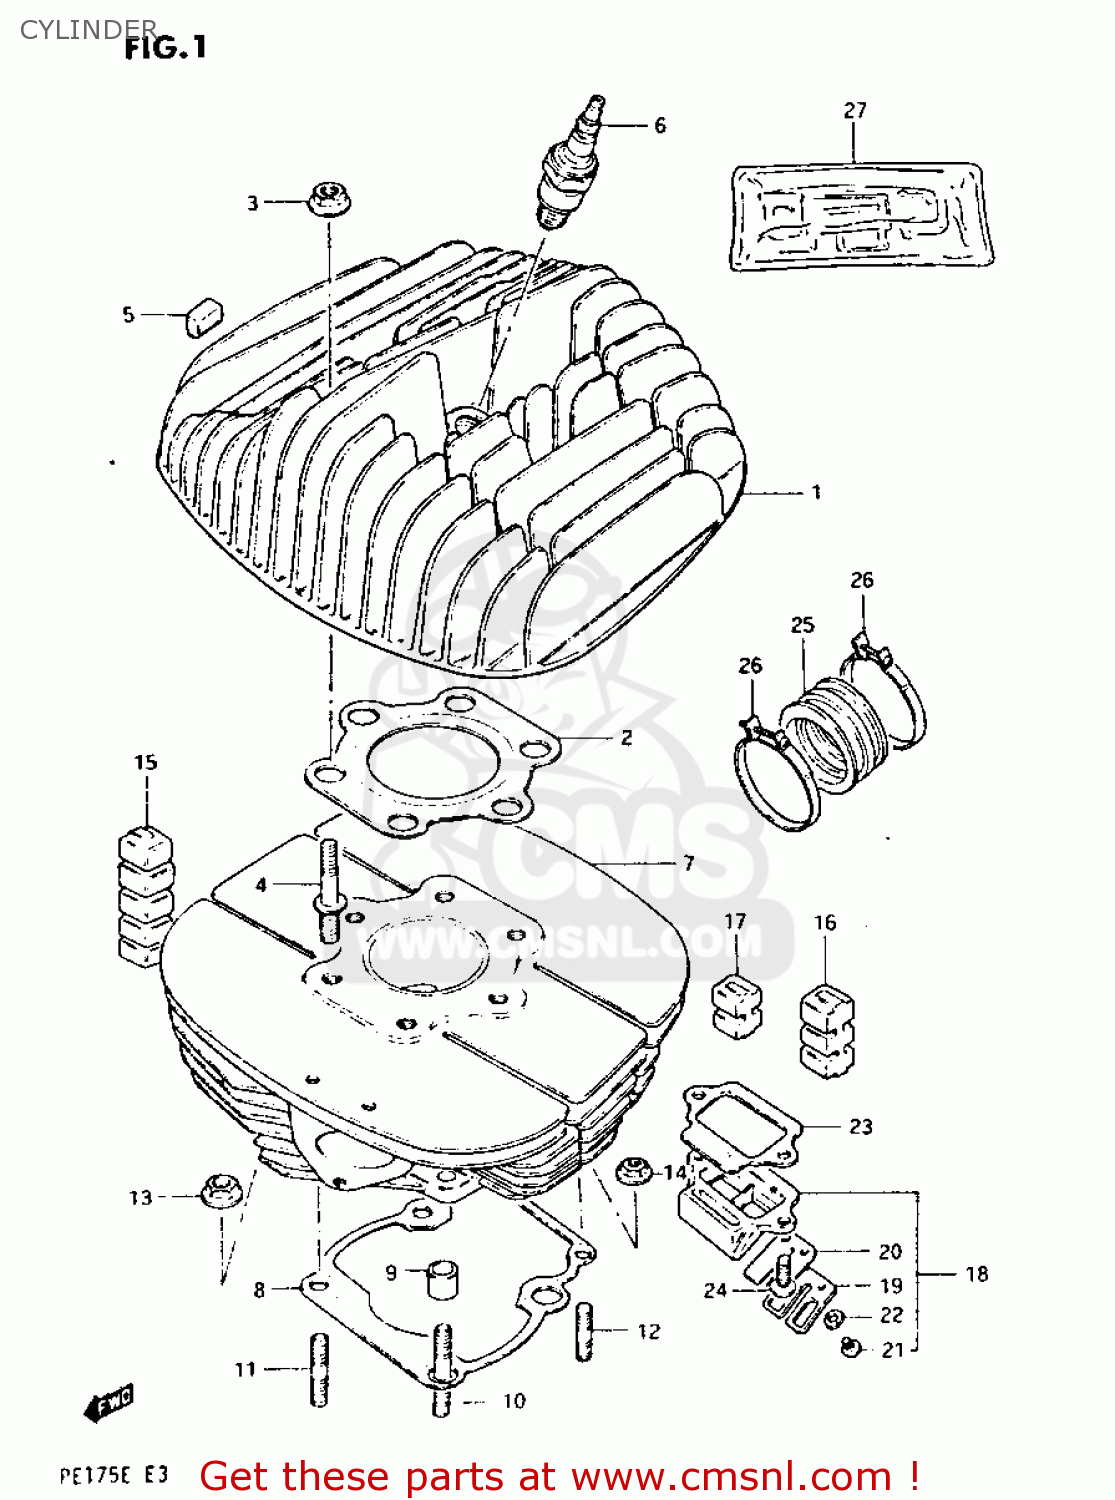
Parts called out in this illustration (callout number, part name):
1	HEAD,CYLINDER
2	GASKET,CYLINDER HEAD (NAS)
3	NUT
4	BOLT,STUD
5	PAD,CYLINDER
6	PLUG,SPARK(B10EGV)
7	CYLINDER
8	GASKET,CYLINDER (MCA)
9	PIN
10	BOLT,STUD
11	STUD 8X25
12	STUD 6X25
13	NUT
14	NUT
15	PAD,CYLINDER
16	PAD,CYLINDER
17	PAD,CYLINDER
18	VALVE ASSY,REED
19	STOPPER,REED VALVE
20	VALVE,REED
21	SCREW
22	WASHER,LOCK
23	GASKET,REED VALVE (MCA)
24	SCREW
25	PIPE,INTAKE
26	CLAMP
27	GASKET SET
